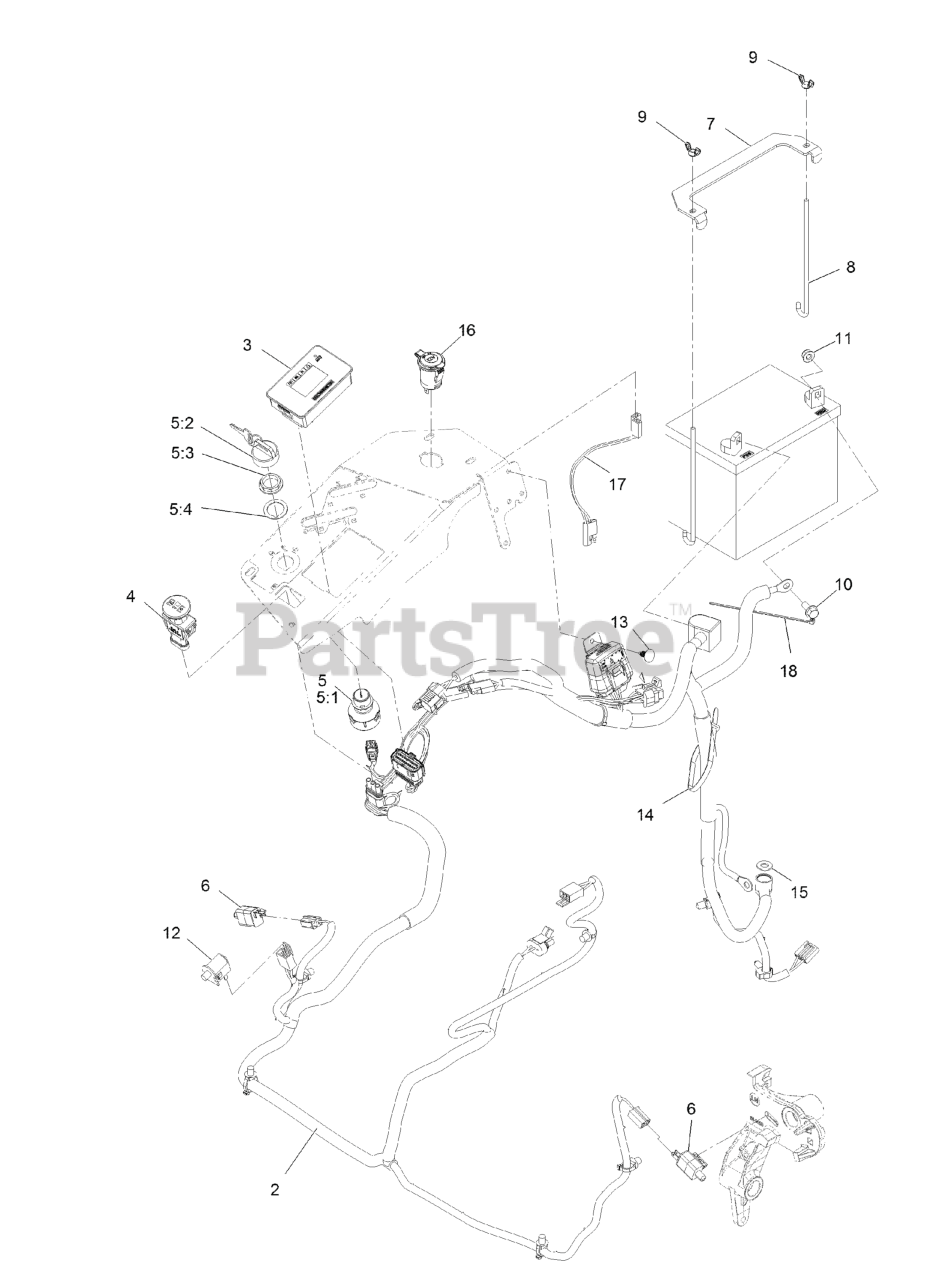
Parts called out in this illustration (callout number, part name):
2	HARNESS-WIRE, MAIN
2:2	FUSE-BLADE, 10 AMP
2:3	FUSE-BLADE, 15 AMP
2:4	FUSE-BLADE, 25 AMP
2:5	CAP-PLUG
3	FUEL/HOUR METER ASM
4	KEYS-IGNITION (SPARE PAIR
4	KEY-IGNITION
6	STRAP-TIE DOWN, BATTERY
7	BOLT-HOLDDOWN
8	WINGNUT
10	CABLE-BATTERY, NEGATIVE
11	SCREW-HHF
12	NUT-HF, NI
13	TIE-CABLE
14	SWITCH-BAIL
16	SWITCH-PTO, 10 AMP
17	SCREW-HWH
18	CABLE-BATTERY, POSITIVE
19	WASHER-FLAT
20	TIE-PLASTIC
22	INDICATOR-LED, RED
23	HARNESS-LIGHT, INDICATOR
24	CLAMP-HOSE
25	INSULATOR-BATTERY
26	INSULATOR-SOLENOID
